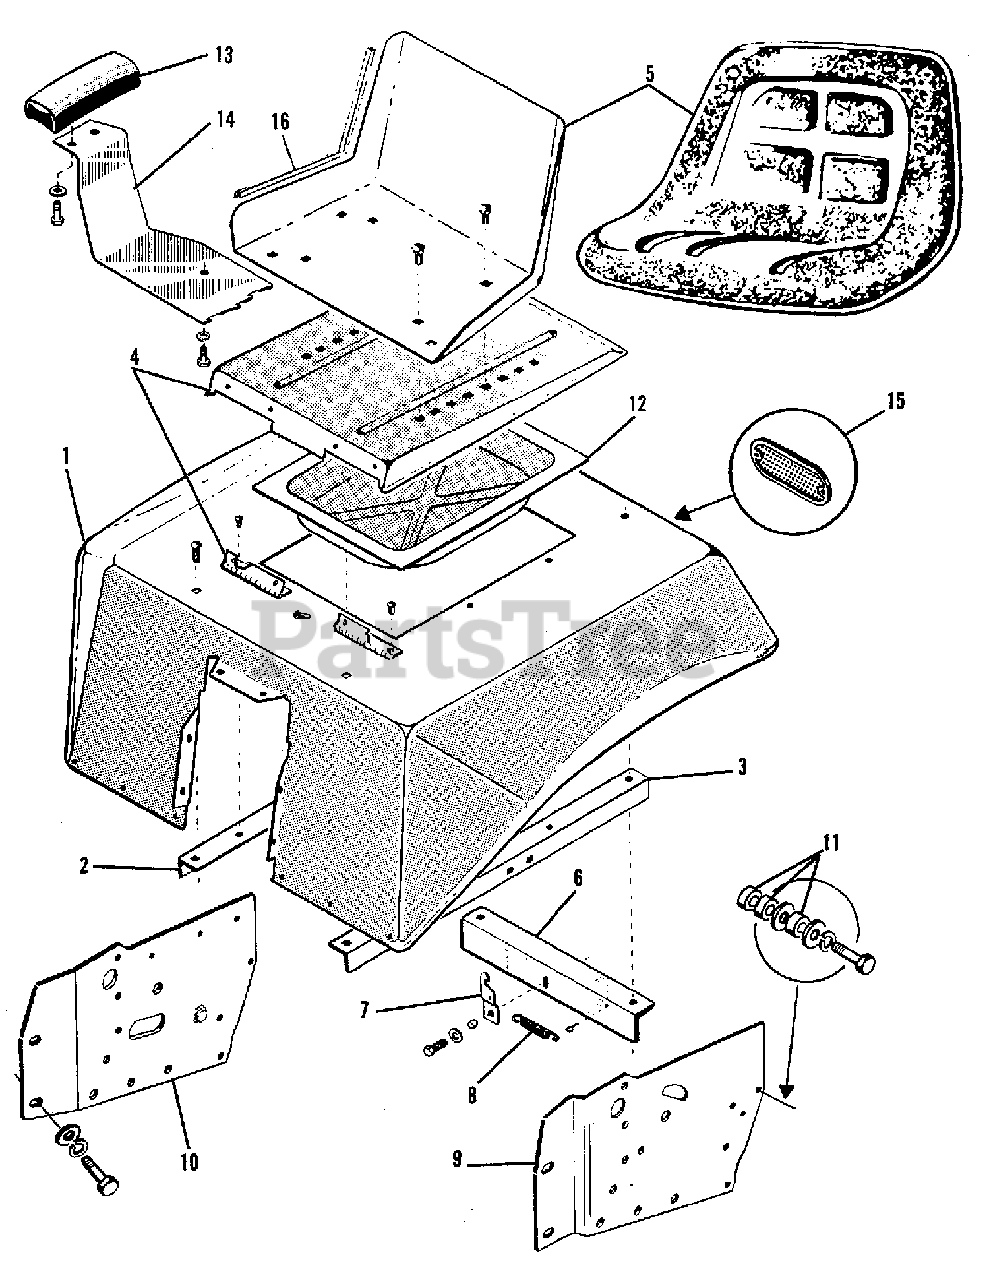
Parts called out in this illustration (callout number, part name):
1	DECK, Seat
1	SCREW, Washer Head., 1/4NC x 1/2
1	CAPSCREW, 5/16NC x 5/8
1	LOCKWASHER, 5/16
1	NUT, 5/16NC
1	CAPSCREW, 5/16NC x 1
2	SUPPORT, Seat Deck, R.H.
2	BOLT, 5/16NC x 3/4
2	LOCKWASHER, 5/16
2	NUT, 5/16NC
3	SUPPORT, Seat Deck, L.H.
3	BOLT, 5/16NC x 3/4
3	LOCKWASHER, 5/16
3	NUT, 5/16NC
4	SUPPORT, Seat
5	PAN, Seat (310 & 312 Models Only)
5	PAD, Seat (310 & 312 Models Only)
5	BOLT, 3/8NC x 1
5	WASHER, Plain, 9/16 x 1 x 12 GA.
5	LOCKWASHER, 3/8
5	NUT, Hex., 3/8NC
5	WASHER, Plain, 25/32 x 2 x 1/4
5	SEAT (All Models Except 310 & 312)
5	CAPSCREW, 3/8NC x 1/2
5	WASHER, Plain, 13/32 x 21/32 x 1/16
6	SUPPORT ASSEMBLY, Seat Deck
6	CAPSCREW, 5/16NC x 1
6	LOCKWASHER, 5/16
6	NUT, 5/16NC
7	LATCH, Seat Support
7	CAPSCREW, 5/16NC x 1
7	LOCKWASHER, 5/16
7	NUT, 5/16NC
7	WASHER, Plain, 13/32 x 7/8 x 14 Ga.
7	WASHER, 5/16 x 1 x 16 Ga.
8	PIN, Cotter, 3/16 x 1
9	PLATE, L.H. Side (F/Variable Speed Transmission Tractors)
9	PLATE, L.H. Side (F/Hydrostatic Transmission Tractors)
9	CAPSCREW, 7/16 NC x 1
9	LOCKWASHER, 7/16
9	CAPSCREW, 7/16 NC x 1, GR8
9	WASHER, 7/16
9	NUT, 7/16NC
10	CAPSCREW, 7/16NC x 1-1/4 (Hydrostatic)
10	PLATE, R.H. Side (F/Variable Speed Transmission Tractors)
10	PLATE, R.H. Side (F/Hydrostatic Transmission Tractors)
10	CAPSCREW, 7/16NC x 1
10	LOCKWASHER, 7/16
10	CAPSCREW, 7/16NC x 1, GR8
10	WASHER, Plain, 7/16
10	NUT, 7/16NC
11	SPACER (F/Variable Speed Transmission Tractors)
11	WASHER, 7/16
11	CAPSCREW, 7/16NC x 2
11	LOCKWASHER, 7/16
12	TRAY, Tool
13	ARM REST, R.H. & L.H.
13	CAPSCREW, 3/8NC x 3/4
13	LOCKWASHER, 3/8
14	BRACKET, Armrest Support
14	CAPSCREW, 3/8NC x 3/4
14	LOCKWASHER, 3/8
15	RELFECTOR, Rear (Red)
16	MOULDING, Trim (Supplied in 19" Length For Standard Model 310 & 312)
